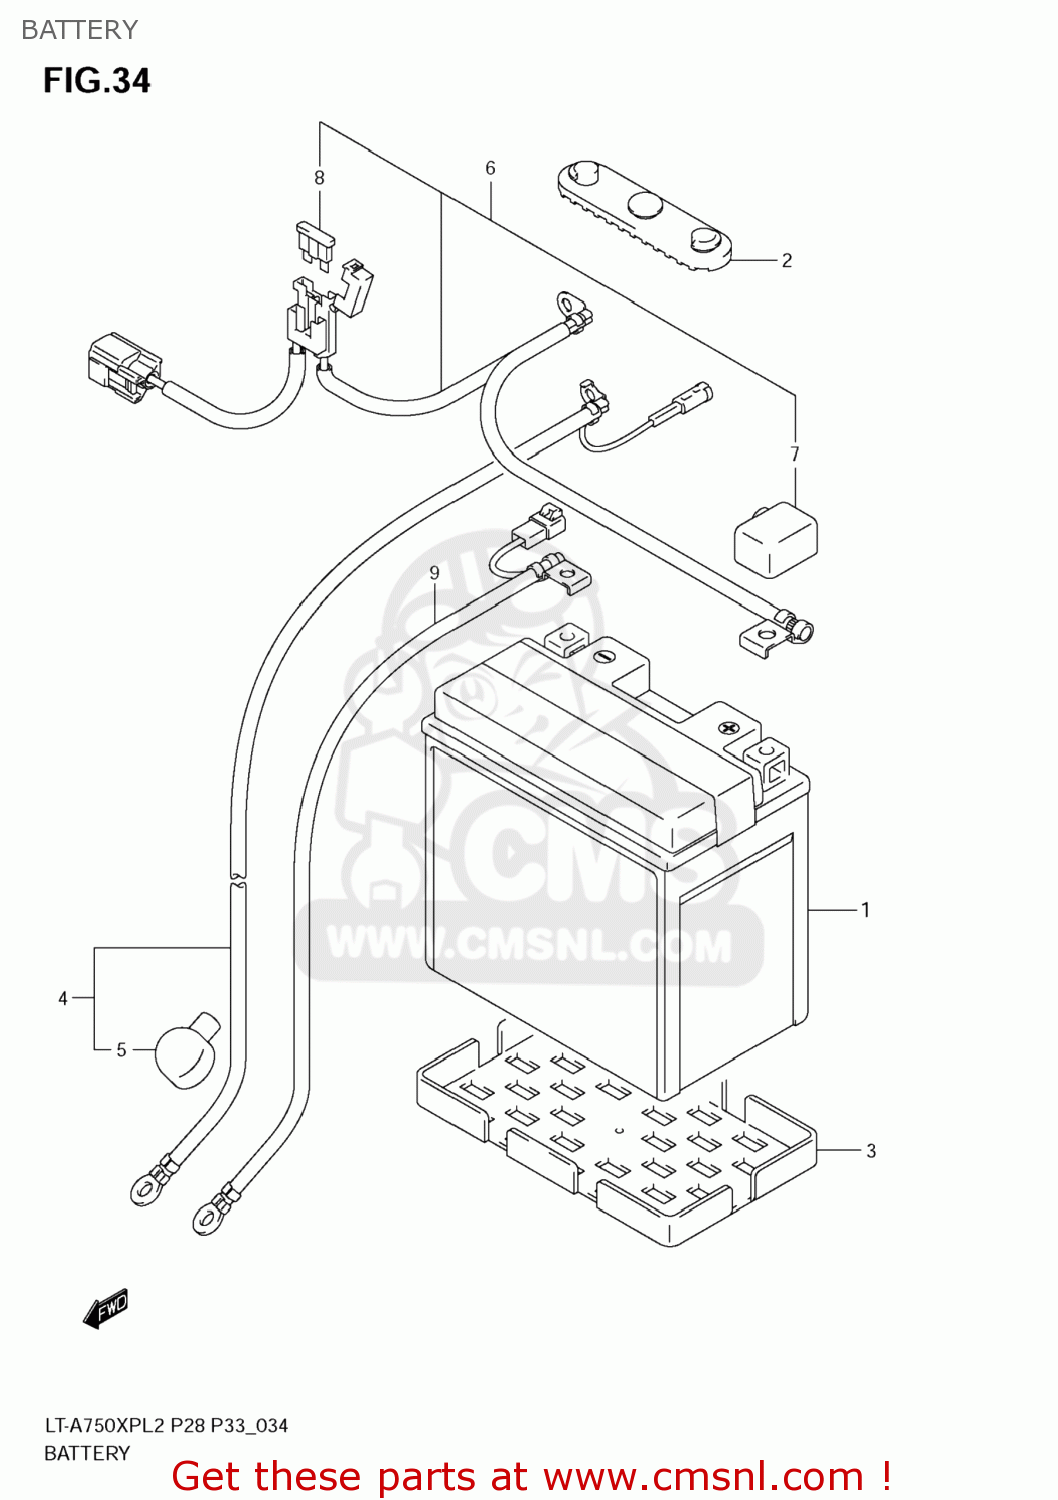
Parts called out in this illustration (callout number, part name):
1	ACCU 6V
2	PROTECTOR,BATTERY
3	PROTECTOR,BATTERY
4	WIRE,STARTER MOTOR
5	CAP,STARTER MOTOR
6	WIRE,BATTERY PLUS
7	CAP,BATTERY PLUS
8	FUSE(40A)
9	WIRE,BATTERY MINUS
